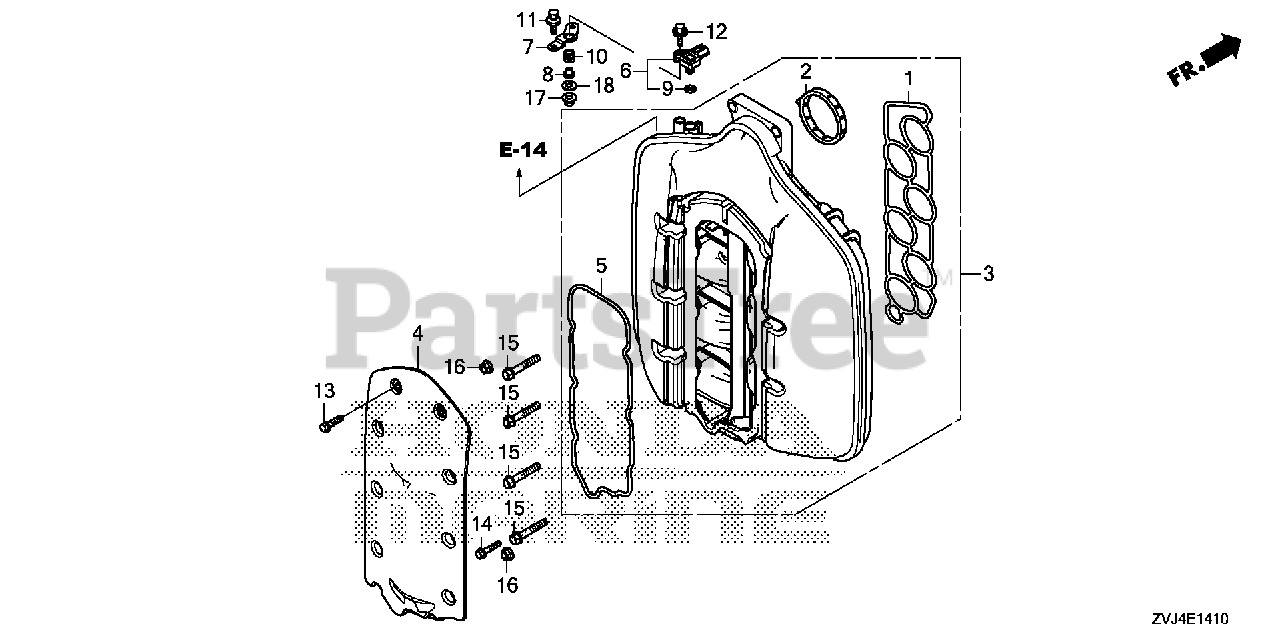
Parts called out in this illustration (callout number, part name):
1	GASKET, IN. MANIFOLD
2	GASKET, THROTTLE BODY
3	MANIFOLD, INLET
4	COVER, IN. MANIFOLD (UPPER) *NH8* (DARK GRAY)
5	GASKET, IN. MANIFOLD UP COVER
6	SENSOR ASSY., MAP
7	STAY, MAP SENSOR
8	COLLAR (5.5X6.8)
11	BOLT-WASHER (5X12)
12	BOLT-WASHER (5X28)
13	BOLT, FLANGE (6X22)
14	BOLT, FLANGE (6X32)
15	BOLT, FLANGE (8X50)
16	NUT, FLANGE (8MM)
17	NUT, FLANGE (5MM)
18	WASHER, PLAIN (5MM)
